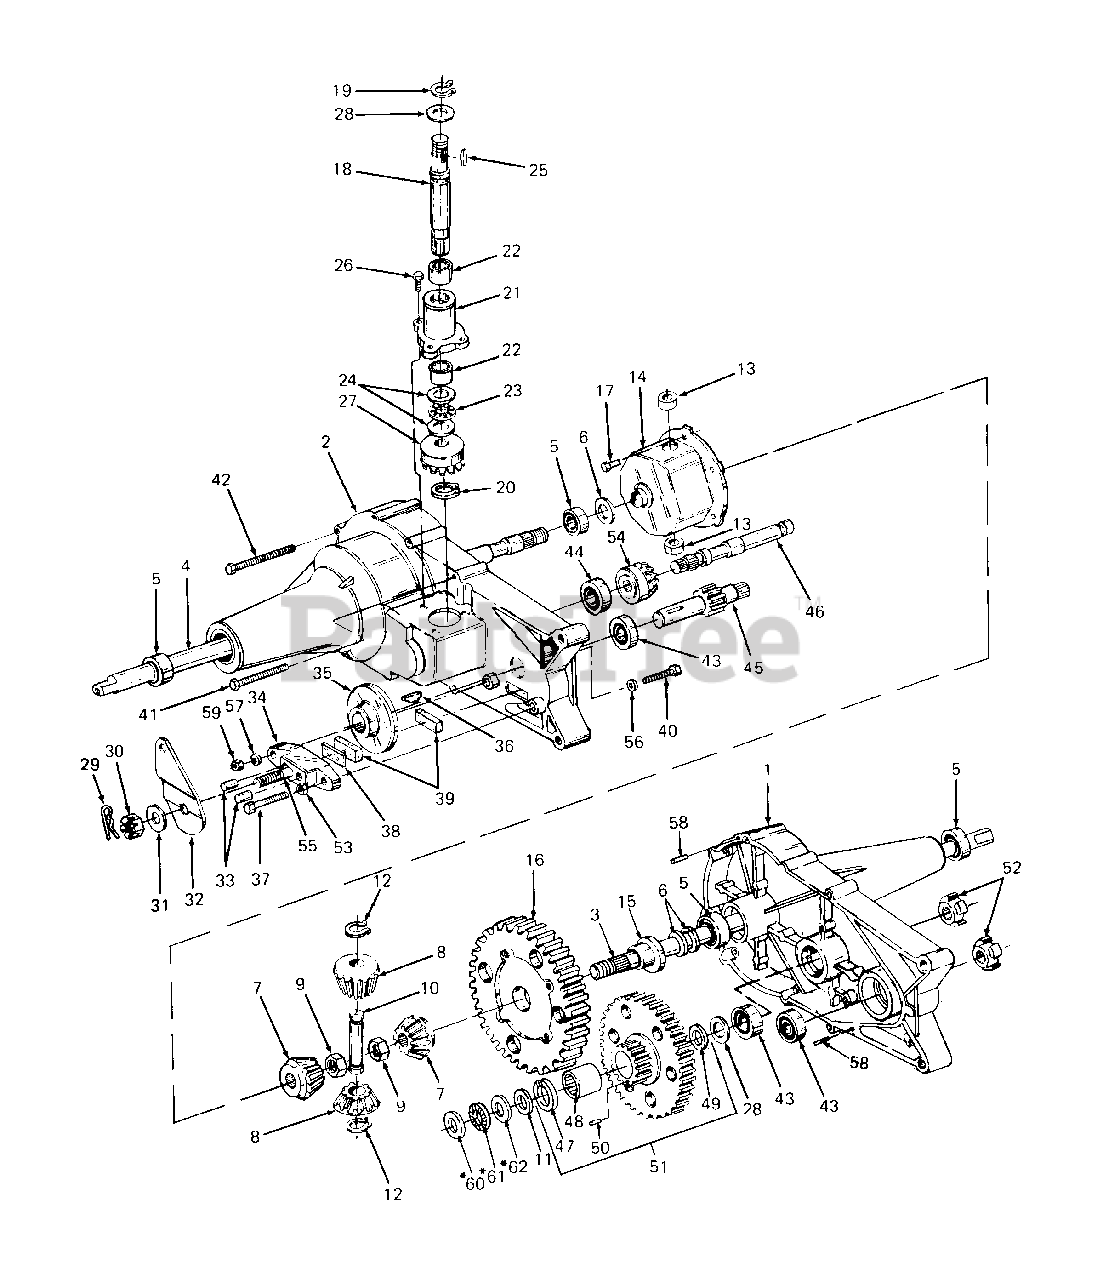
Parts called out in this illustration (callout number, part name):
1	Housing Half, LH
2	Housing Half, RH
5	Bearing, Ball
6	Washer, Flat, .76 X 1.5 X .306 Thk Hdn
7	Gear, Miter
8	Gear, Miter
9	Nut, Hex Jam Patch Lock, 1/2-20
10	Shaft, Cross
11	Washer, Flat, .62 ID X 1.0 OD X .050 Thk
12	Ring, Snap
13	Bearing, Thrust
14	Housing Assy, Differential
15	Bearing, Flange, .75 ID X .587
16	Gear, Differential, 72 Tooth
17	Bolt, Hex Wash Hd Patch, 1/4-28 X .62 Lg
18	Shaft, Input
19	Ring, Snap
20	Ring, Retaining, Ext, 7/16 Dia
21	Bearing, Input Housing
22	Bearing, Needle, 5/8 ID X .50 Lg
23	Bearing, Thrust
24	Washer, Flat, 5/8 ID X 1.12 OD X .030 Thk
25	Key, #4 Hi-Pro, 3/32 X 5/8 Dia Hdn
26	Screw, Hex Patch Lock, 1/4-20 X 3/4 Lg
27	Gear, Input Pinion, 17 Tooth
28	Washer, Flat, .62 ID X 1.0 OD X .050 Thk
29	Pin, Cotter
30	Nut, Castle, 5/16-24
31	Washer, Flat, .343 X .88 X .062 Thk
32	Arm, Brake Actuator
33	Pin, Actuating, 5/16 Dia
34	Yoke, Brake
35	Disc, Brake
36	Key, Hi-Pro, 3/16 X 5/8 Dia
37	Screw, Hex Patch Lock, 1/4-20 X 1.5 Lg
38	Plate, Puck
39	Puck, Brake
40	Screw, Hex Cap, 1/4-20 X 1.5 Lg
41	Screw, Hex Self-Tapp, 1/4-20 X 2.0 Lg
42	Screw, Hex Self-Tapp, 1/4-20 X 2.75 Lg
43	Bearing, Ball
44	Bearing, Ball
45	Shaft, Pinion w/11 Tooth Gear
46	Shaft, Drive
47	Bearing, Bronze Thrust
48	Bearing, Needle
49	Seal, Grease
50	Pin, Dowel, 3/32 Dia X .25 Lg
51	Gear Assy, 60 & 17 Tooth
52	Coupling
53	Nut, Hex Jam, 1/4-20
54	Gear, Drive Pinion, 17 Tooth
55	Bolt, Square Hd, 5/16-24
56	Washer, Flat, .265 X .938 X .12 Thk
57	Washer, Lock, 1/4
58	Pin, Roll, 3/16 Dia X .50 Lg
59	Nut, Hex, 1/4-20
60	Washer, Flat, .62 ID X 1.12 OD X .060 Thk
61	Bearing, Thrust
62	Washer, Flat, .62 ID X 1.12 OD X .030 Thk
